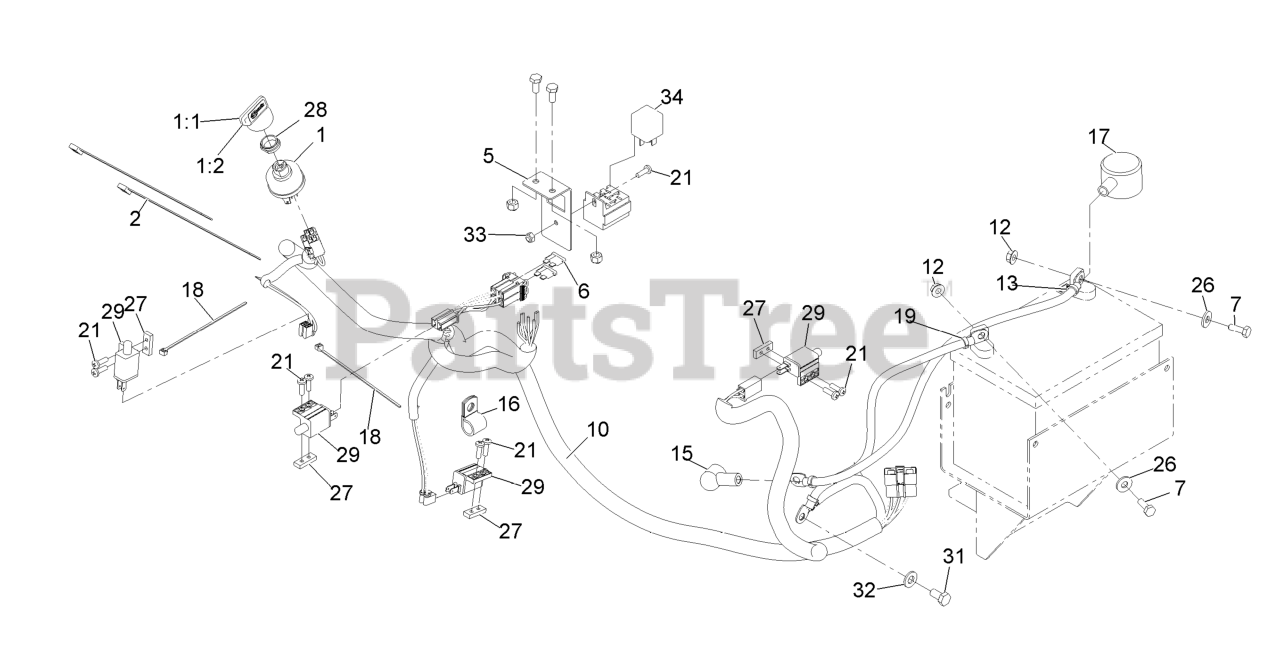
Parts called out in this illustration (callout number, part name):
1:1	KEYS-IGNITION (SPARE PAIR
1:2	KEY-IGNITION
2	TIE-PLASTIC
5	BRACKET-FUSE AND RELAY
6	FUSE-BLADE TYPE, 20 AMP
7	SCREW-HH
13	ASM,POSITIVE BATTERY CABL
15	INSULATOR-SOLENOID
16	CLIP-LOOM
17	INSULATOR-BATTERY
18	TIE-CABLE
19	CABLE-BATTERY, NEGATIVE
21	SCREW-PPH
26	WASHER-FLAT
27	PLATE-TAPPED
28	NUT-SWITCH, IGNITION
29	SWITCH-OPEN, NORMALLY
31	SCREW-HH
32	WASHER-PLAIN
33	NUT-LOCK, NI
